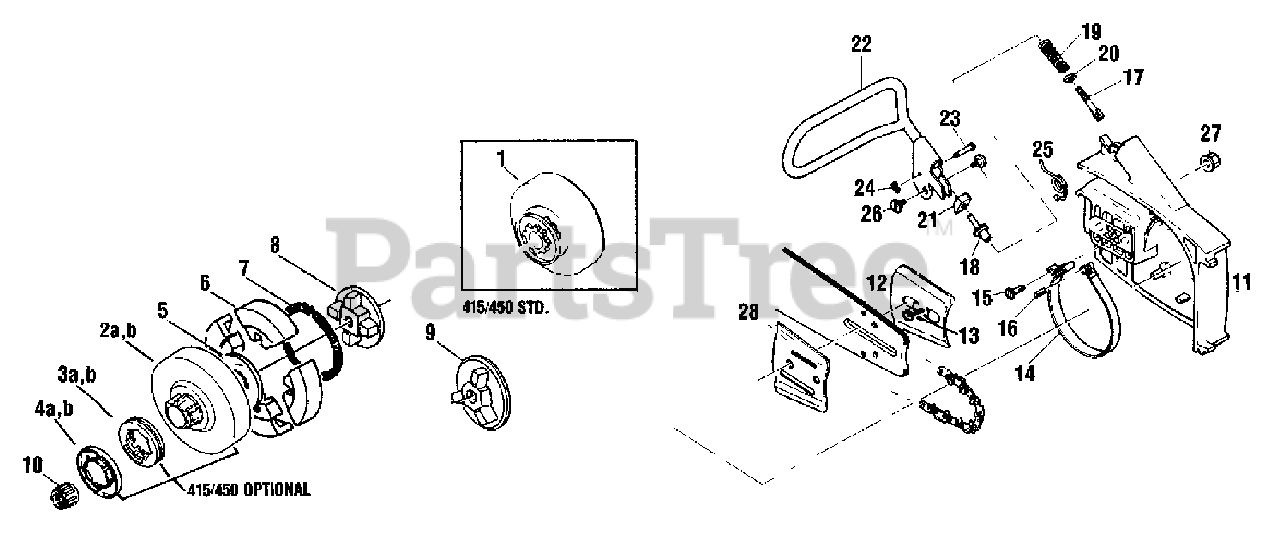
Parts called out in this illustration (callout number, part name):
1	DRUM, CLUTCH
2A	DRUM, CLUTCH
2B	DRUM, CLUTCH
3A	SPROCKET, 0.325 RIM
3B	RIM SPROCKET
4A	COVER, RING
4B	COVER, RING
5	BOSS, CLUTCH A
6	SHOE, CLUTCH
7	SPRING, CLUTCH
8	BOSS, CLUTCH B
9	HUB, CLUTCH - OUTER
10	BEARING, NEEDLE
11	CLUTCH COVER ASSY
12	PLATE, GUIDE - OUTER
14	BAND, BRAKE
15	BOLT
16	PIN, SPRING
17	ROD, ADJUST
18	SCREW, ADJUST
19	SPRING, BRAKE
22	LEVER
23	STOPPER PIN
24	RING, RETAINING
25	RELIEF SPRING
26	BOLT, LEVER
27	NUT
28	PLATE, GUIDE - INNER
